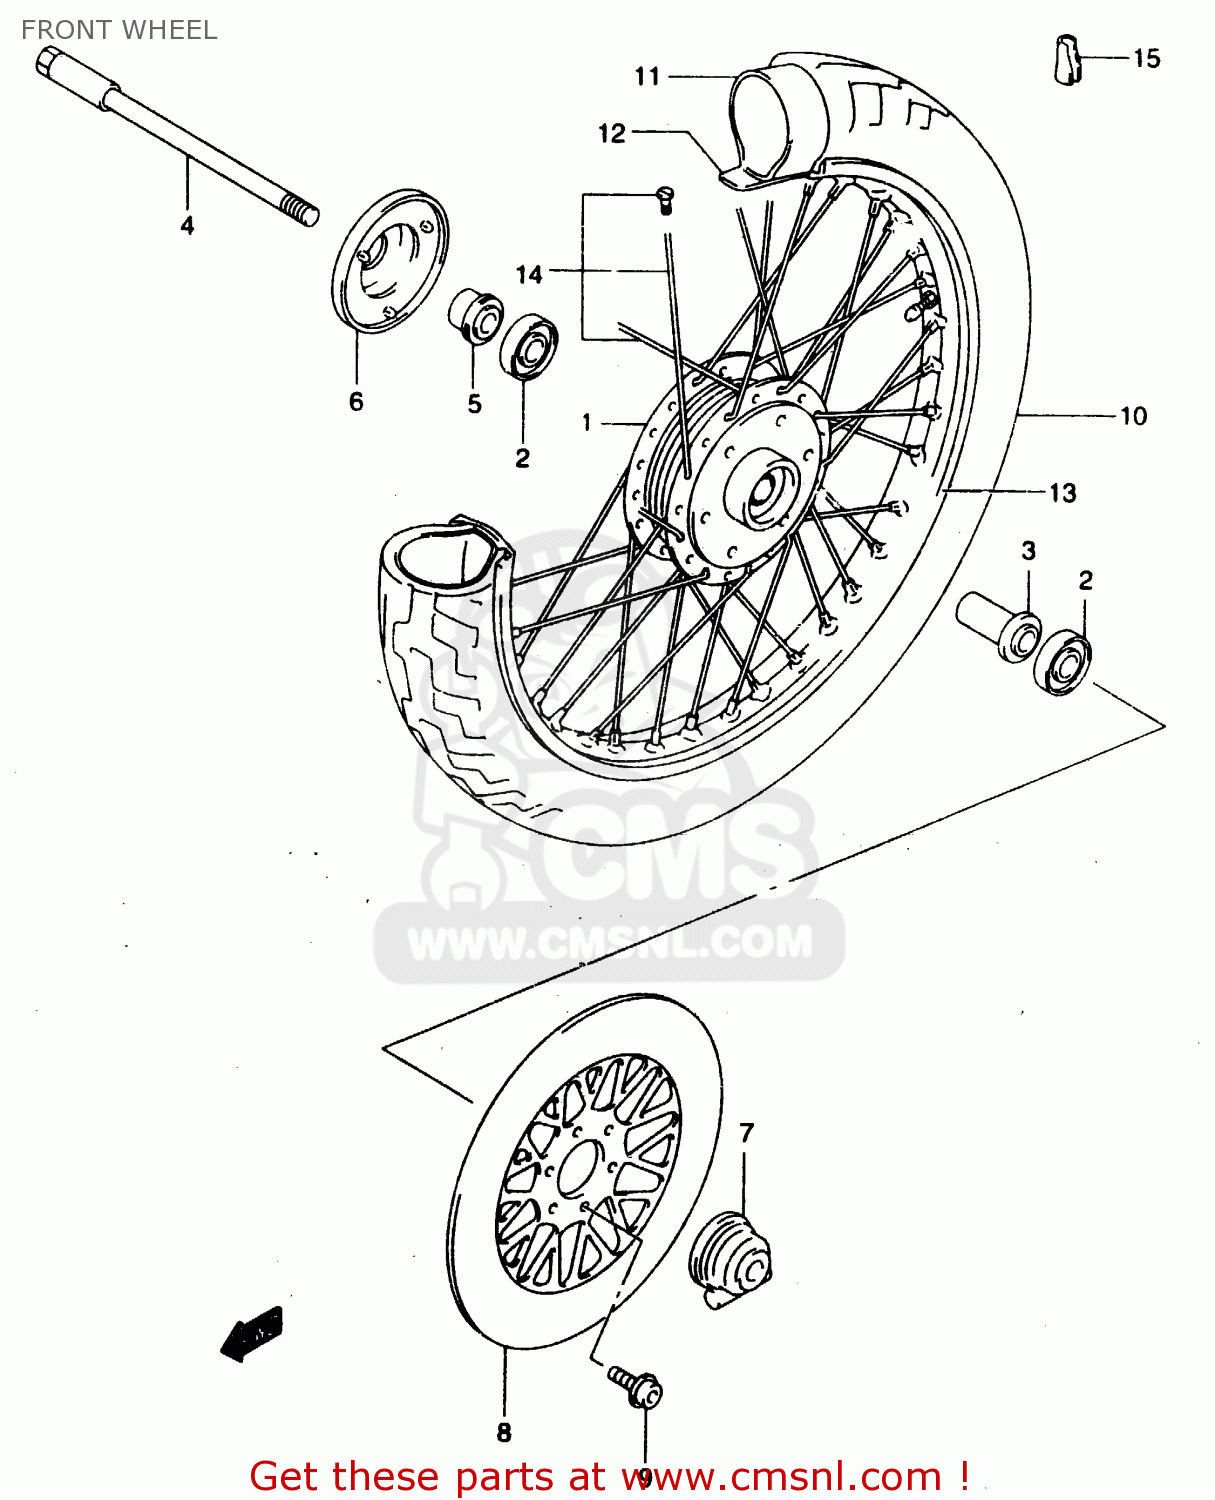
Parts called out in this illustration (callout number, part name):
1	HUB,FR WHEEL
2	BEARING
3	SPACER,FR HUB BEARING
4	AXLE,FR
5	SPACER,FR HUB BEARING,R
6	COVER,FR HUB,R
7	BOX ASSY,SPEEDOMETER GEAR
8	DISC,FR BRAKE
9	BOLT(8X30)
10	TIRE,FR(110/90-16)
11	TUBE ASSY,WHEEL INNER
12	PROTECTOR,WHL INR TUBE
13	RIM,FRONT WHEEL (16XMT2)
14	SPOKE SET,FR WHEEL
15	BALANCER,WHEEL (B)
